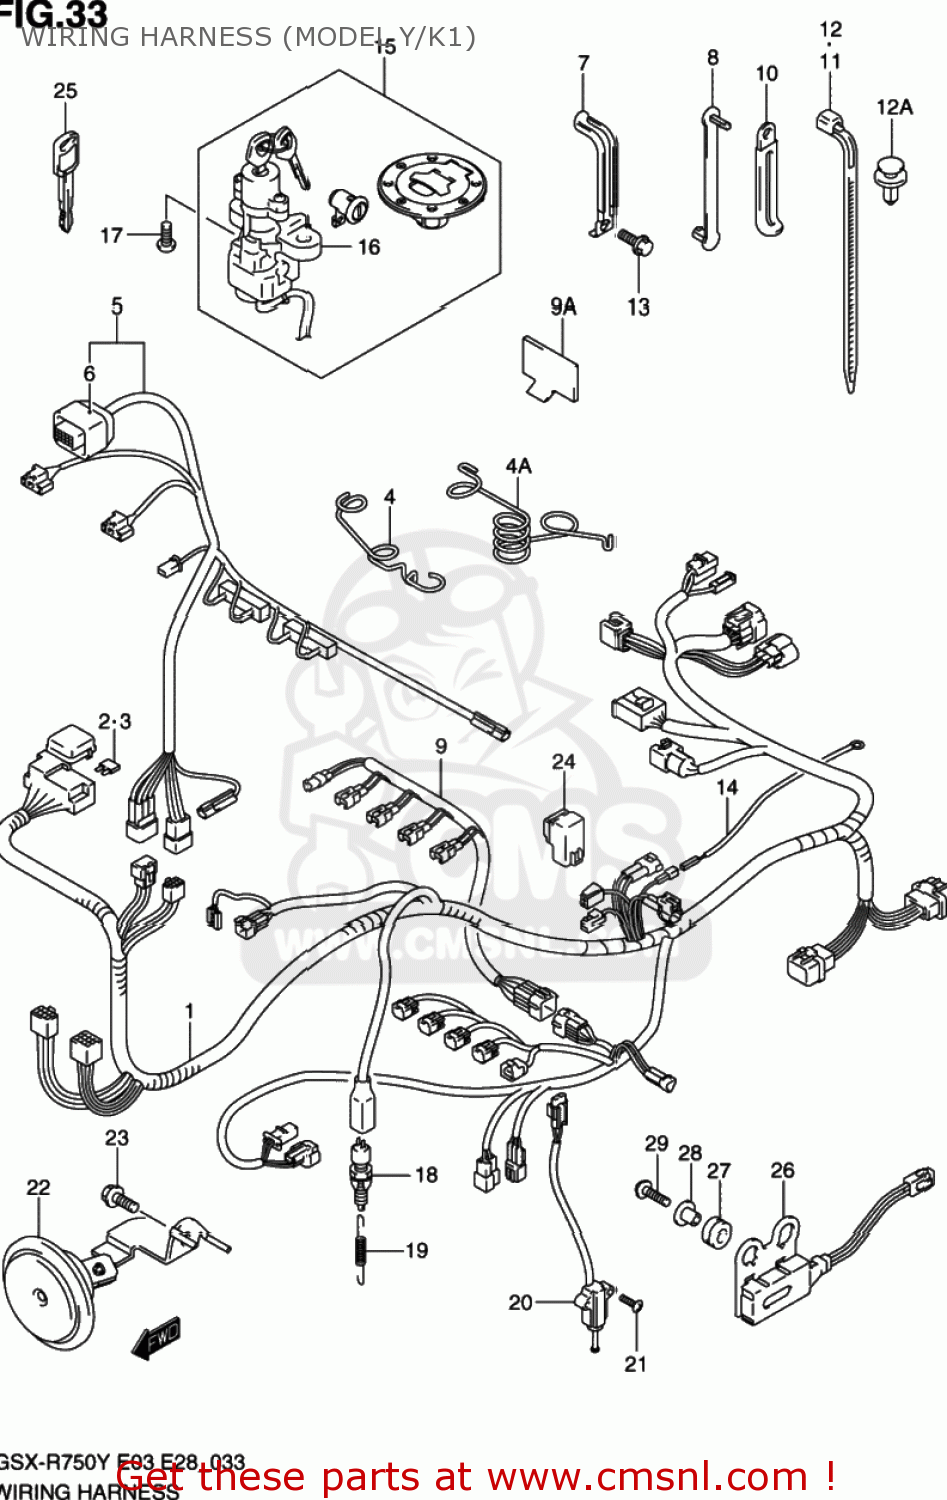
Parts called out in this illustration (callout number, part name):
1	HARNESS,WIRING NO.1
2	FUSE(10A)
3	FUSE(15A)
4	GUIDE,WIRING HARNESS
4A	GUIDE,WIRING HARNESS
5	HARNESS,WIRING NO.2
6	COVER,SPEEDOMETER COUPLER
7	CLAMP,WIRING HARNESS
8	CLAMP(L:63)
9	WIRE,INJECTOR LEAD
9A	PROTECTOR,WIRING HARNESS
10	CLAMP(L:65)
11	CLAMP(L:125)
12	CLAMP
12A	CLIP
13	BOLT
14	WIRE,OIL PRESSURE SWITCH LEAD
15	LOCK SET
16	LOCK ASSY,STEERING
17	BOLT(8X20)
18	SWITCH ASSY,STOP LAMP
19	SPRING
20	SWITCH ASSY,SIDE STAND
21	BOLT
22	HORN ASSY
23	BOLT
24	RELAY ASSY
25	KEY,BLANK
26	RESISTOR ASSY
27	CUSHION
28	SPACER(6.5X10X11.6)
29	SCREW(6X25)
